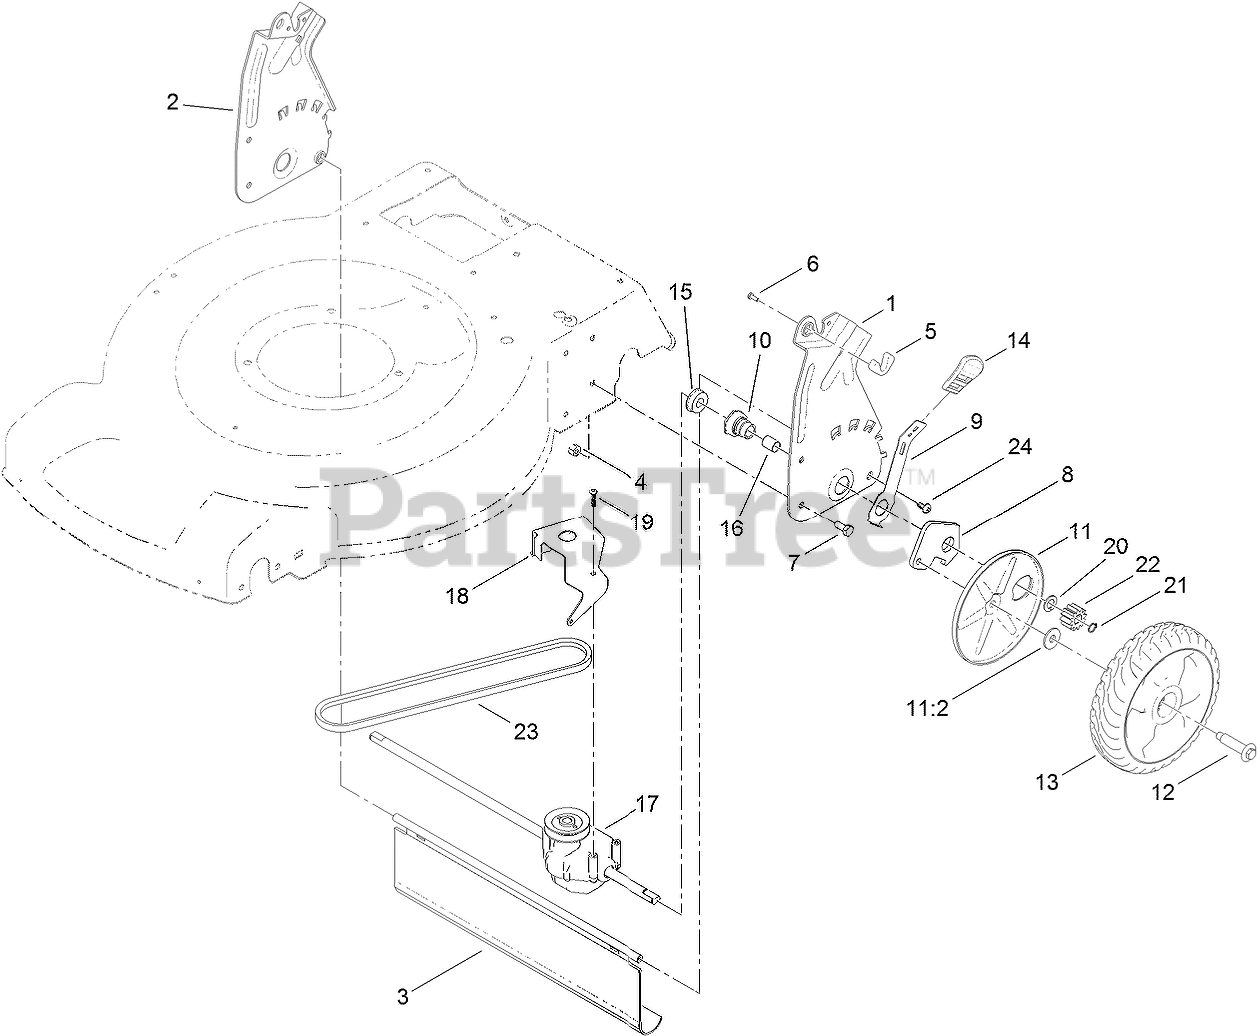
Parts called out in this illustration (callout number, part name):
1	PLATE-REAR, LH (HOC)
2	PLATE-REAR, RH (HOC)
3	SHIELD-TRAILING
4	NUT-LOCK, NI
5	ANCHOR-BAG
6	Screw-PPH
7	SCREW-HH
8	ARM-PIVOT, REAR
9	ARM-SPRING
10	RETAINER-BUSHING, HOC
11	WHEEL COVER ASM
11:2	WASHER-STEPPED
12	BOLT-SHOULDER
13	8 INCH WHEEL GEAR ASM
14	KNOB-HOC
15	BEARING-BALL
16	BUSHING-SLEEVE
17	TRANSMISSION
18	BRACKET-TRANSMISSION
19	SCREW-PAN HEAD, T20
20	WASHER-THRUST
21	RING-RETAINING
22	GEAR-PINION
23	BELT-V
24	SCREW-PTH
